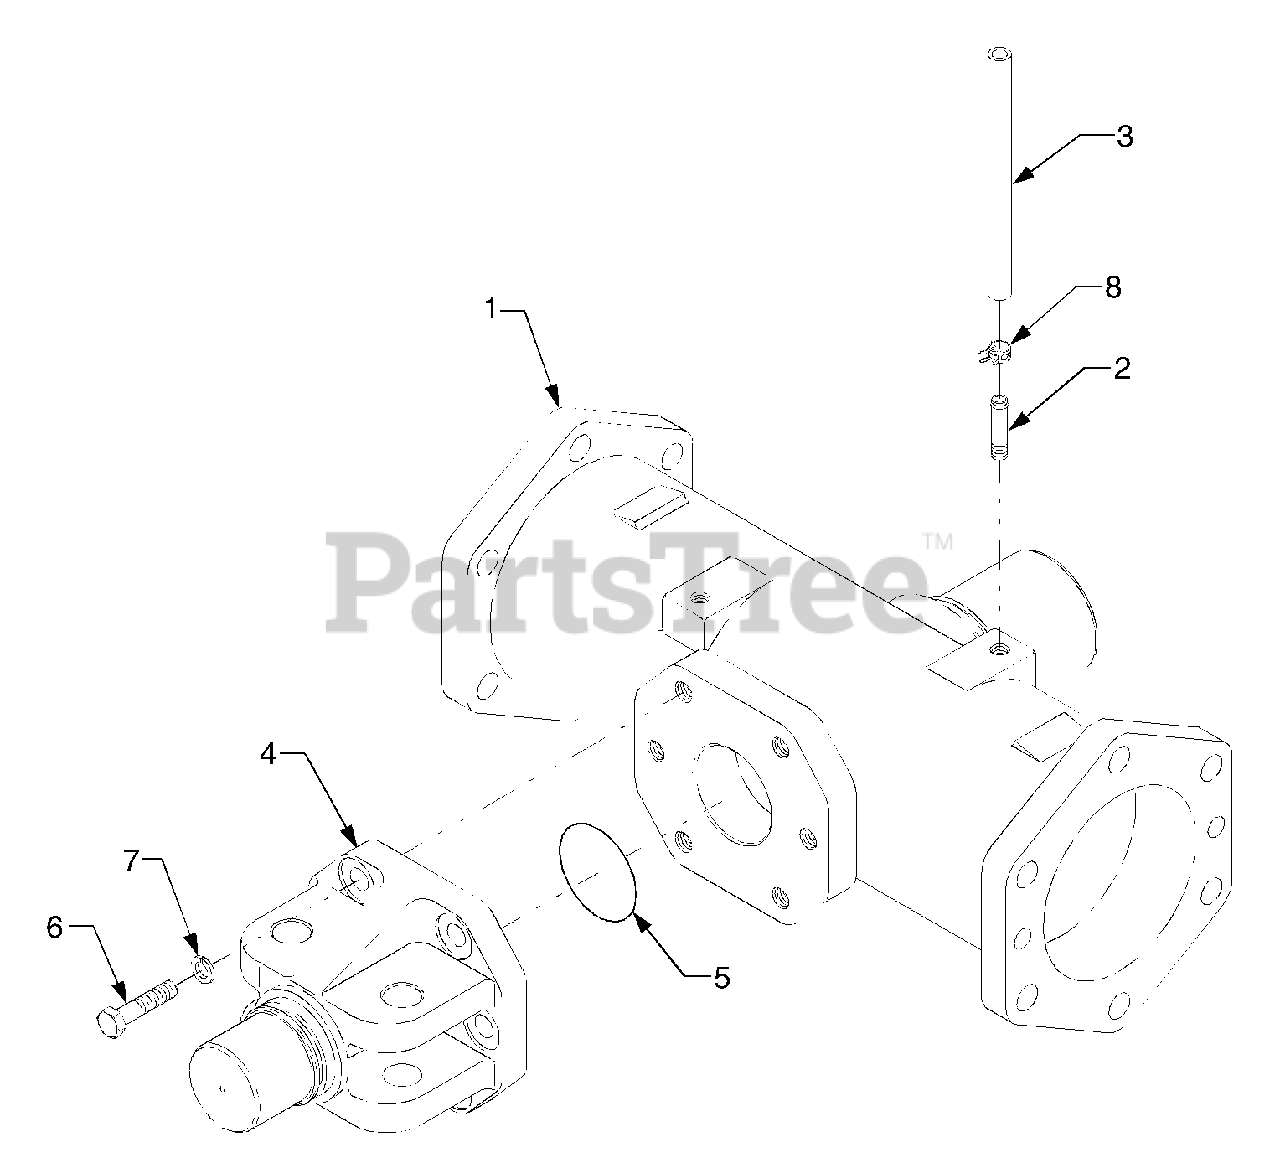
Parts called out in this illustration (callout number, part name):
1	Support, Front Axle
3	Pipe, Over Flow
7	Washer, Spring
